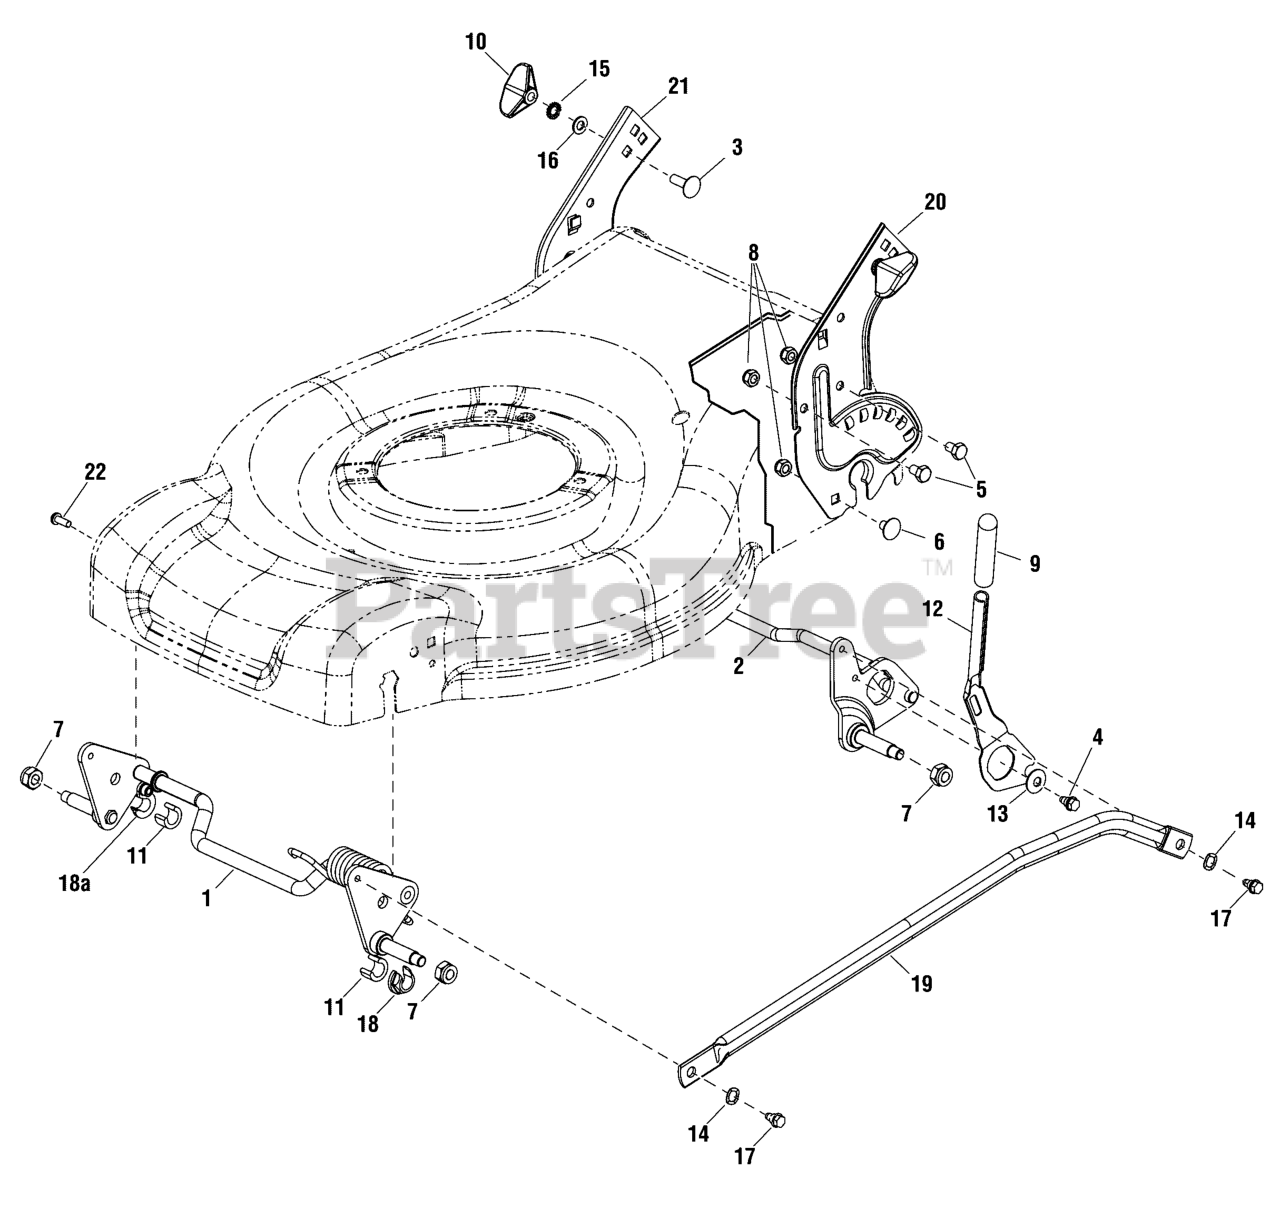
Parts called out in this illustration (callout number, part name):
1	CROSSBAR ASSEMBLY, Front
2	CROSSBAR ASSEMBLY, Rear
3	SCREW, Head, M8 x 25 DIN 603
4	SCREW, TT, 1/4-20 x 1/2
5	SCREW, M8 x 12 DIN 933
6	BOLT, Carriage, M8 x 12 DIN 933
7	NUT, M10 x 1.25 DIN 985
8	NUT, M8 DIN 985
9	KNOB, Adjuster, 0.50 x 3.54
10	NUT, WING, M8 x 1.25
11	SPACER, Clip, 1/2 x 500
12	LEVER, Height Adjustment
13	WASHER, Belleville, 0.340X0.872X0.060
14	WASHER, Wave, 0.390 x 3/4
15	WASHER, B8,4 DIN 6798
16	WASHER, Flat, A8.4 DIN 125
17	SCREW, Shoulder, 1/4-20 x 1/2
18	BEARING, Flange Hex, D 0.500
18A	BEARING, Flange, D 0.500
19	LINK, Single Lever
20	BRACKET ASSEMBLY, LH
21	BRACKET ASSEMBLY, RH
22	SCREW, M6 x 16
